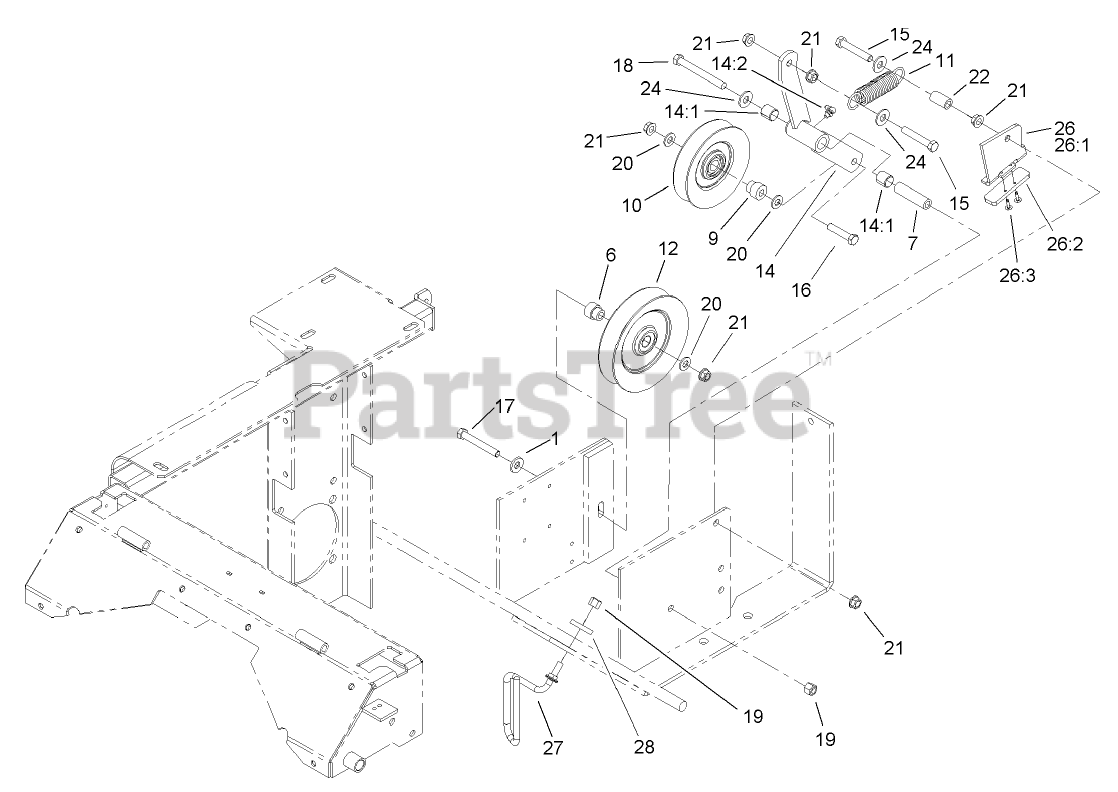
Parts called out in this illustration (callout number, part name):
1	WASHER-BELLEVILLE
6	Bushing-Idler
7	BUSHING-PIVOT, IDLER
9	BUSHING-IDLER
10	Idler
11	SPRING-EXTENSION
12	PULLEY-IDLER
14	Arm ASM
14:1	SLEEVE-BEARING
14:2	FITTING-GREASE, 90 DEG
15	SCREW-HH
16	SCREW-HH
17	SCREW-HH
18	SCREW-HH
19	NUT-LOCK, NI
20	WASHER-FLAT
21	NUT-HHF, WHIZ
22	SPACER
24	WASHER-FLAT
26	Travel Limiter ASM
26:1	Plate-Limiter, Pulley
26:2	PAD-BUMPER
26:3	RIVET
27	Guide-Belt
28	WASHER
